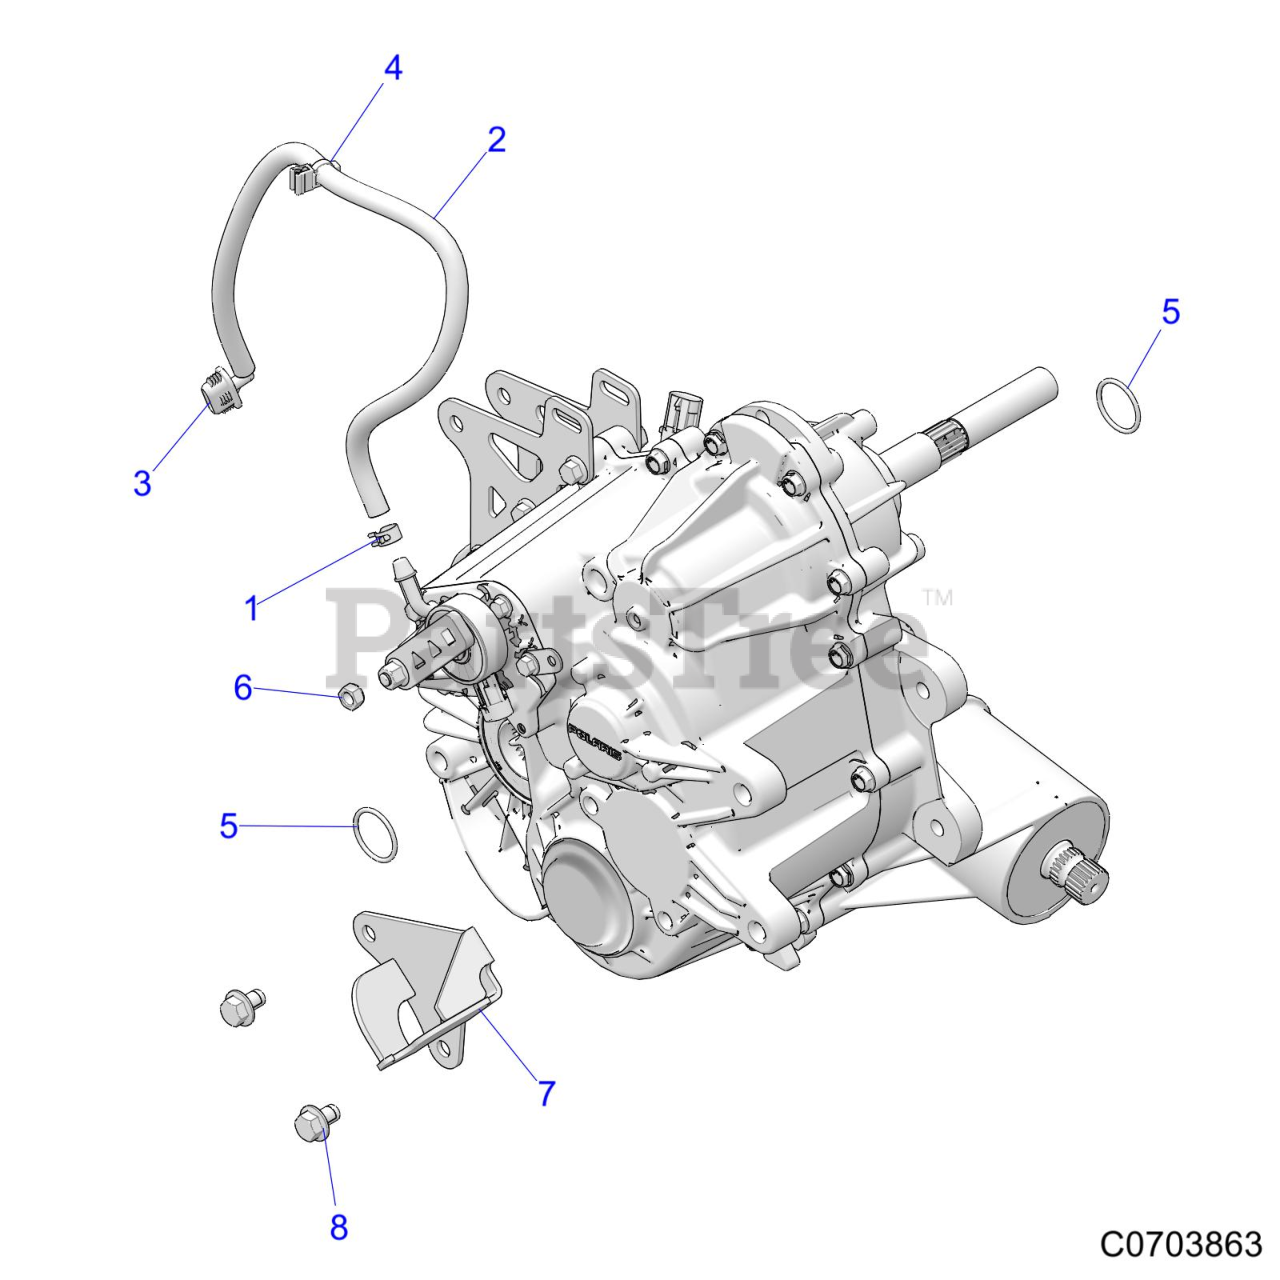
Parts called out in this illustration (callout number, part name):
1	CLAMP-HOSE, 17/32, GREEN
2	FUEL LINE-50 CM
3	FITTING-VENT LINE,90
4	STRAP-CABLE TIE W/EDGE CLIP
5	O-RING,-123
6	NUT,NYLOK M8X1.25(10) *
7	BRKT-CABLE,SHIFT
8	BOLT-M10X1.25X16,HXHD,FLG
